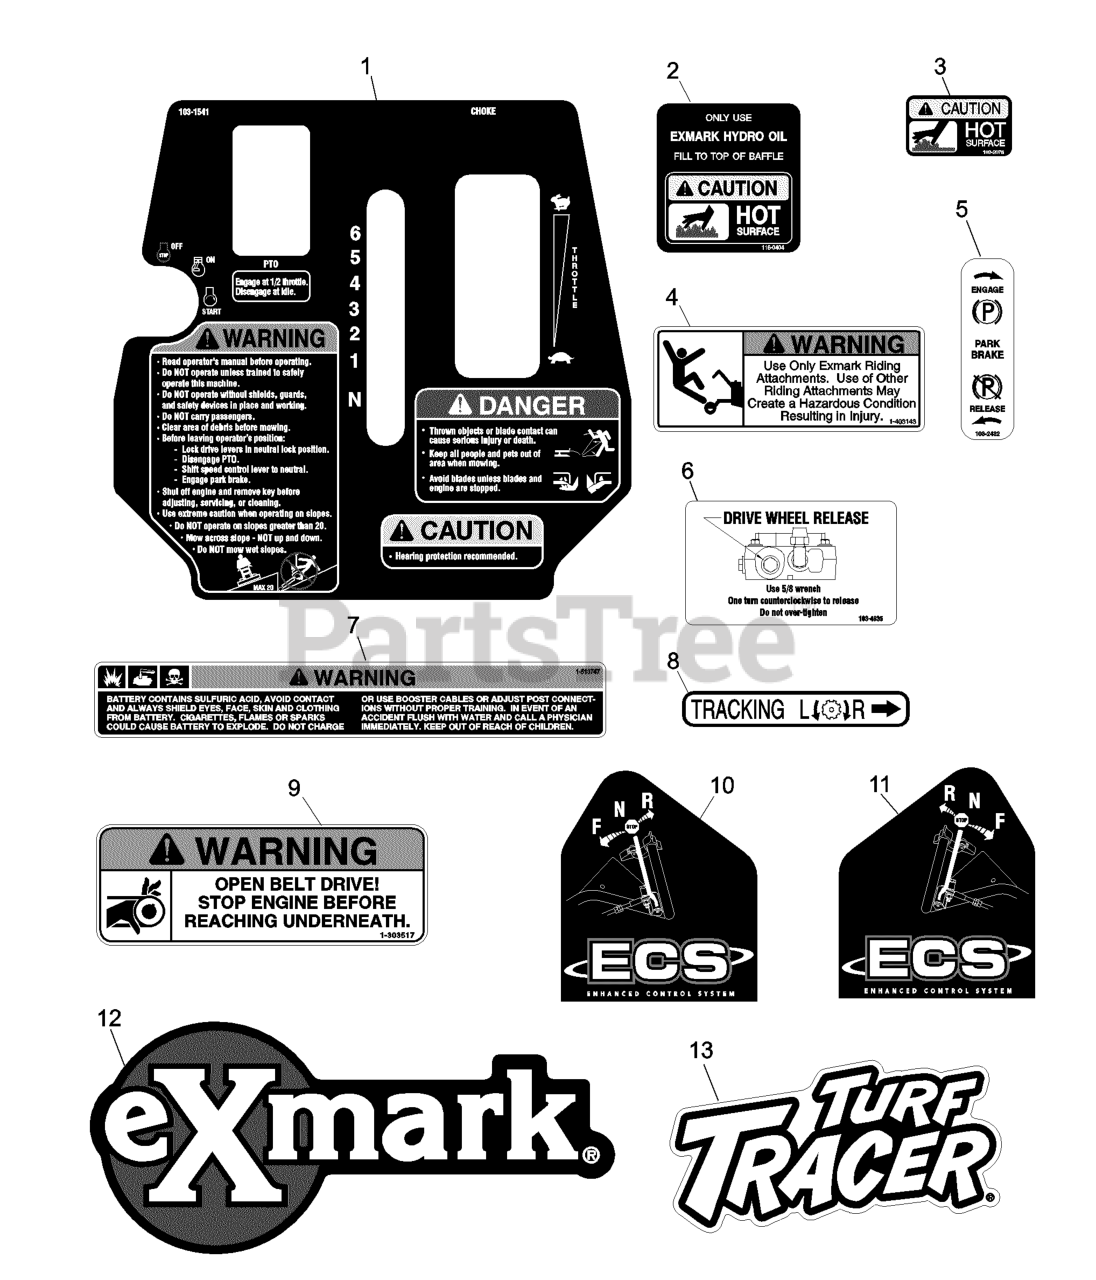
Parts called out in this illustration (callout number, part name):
1	DECAL,CONSOLE
2	DECAL-HYDRAULIC TANK
3	DECAL-CAUTION
4	DECAL,PARKING BRAKE
5	DECAL-BATTERY
6	DECAL,NEUTRAL LOCK
7	DECAL,TRACKING ADJUST
8	DECAL,SULKY WARNING
9	DECAL,DRIVE RELEASE
10	DECAL,BELT DRIVE
11	DECAL,EXMARK LOGO
12	DECAL,TTH MODEL
